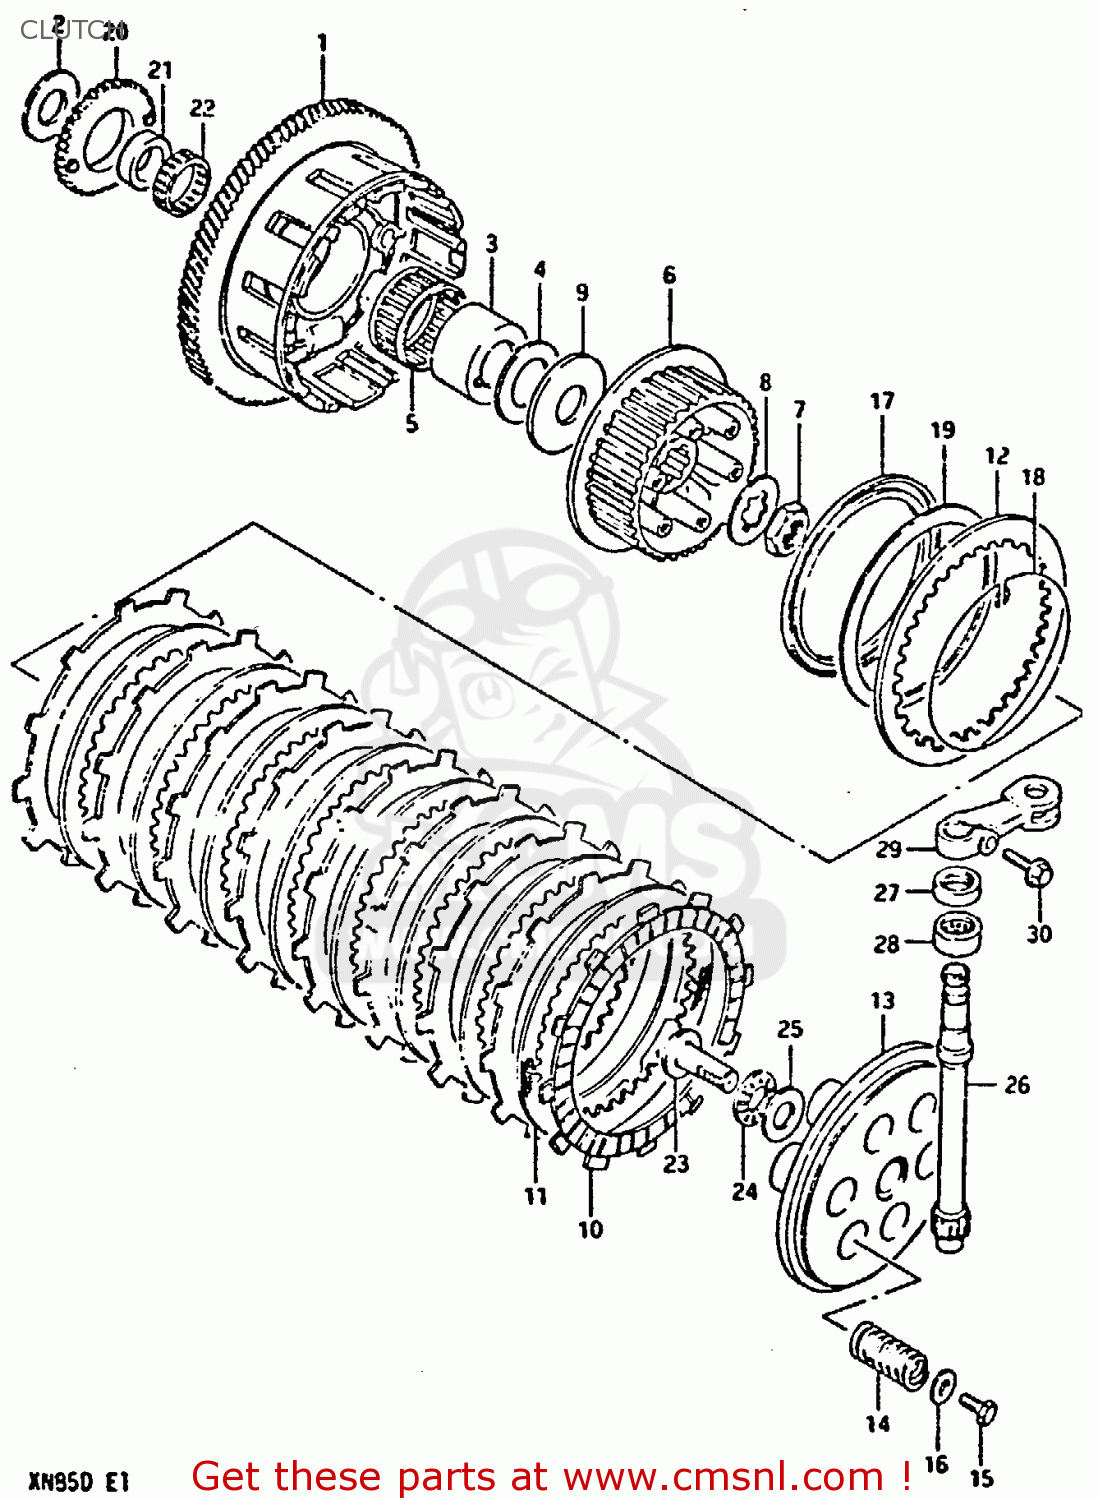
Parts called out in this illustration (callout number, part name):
1	GEAR ASSEMBLY,PRIMARY DRIVE
2	WASHER
3	SPACER
4	SHIM(T:1.00)
5	BEARING(51X56X28)
6	HUB,CLUTCH SLEEVE
7	NUT
8	WASHER,LOCK
9	WASHER(25X66X3.5)
10	PLATE,CLUTCH DRIVE (MCA)
11	PLATE,CLUTCH DRIVEN (NAS)
12	PLATE,CLUTCH DRIVEN(T:2.0) (NAS)
13	DISC,CLUTCH PRESSURE
14	SPRING
15	BOLT, UPPER
16	WASHER
17	SEAT,WAVE WASHER
18	RING,STOPPER
19	WASHER
20	GEAR,ENG OIL PUMP DRIVE(NT:34)
21	SPACER,OIL PUMP DRIVE GEAR
22	BEARING(36X40X10)
23	RACK,CLUTCH RELEASE
24	BEARING(15X28X2)
25	WASHER
26	PINION,CLUTCH RELEASE
27	OIL SEAL
28	BEARING(15X22X12)
29	ARM,CLUTCH RELEASE
30	BOLT (6X20)
